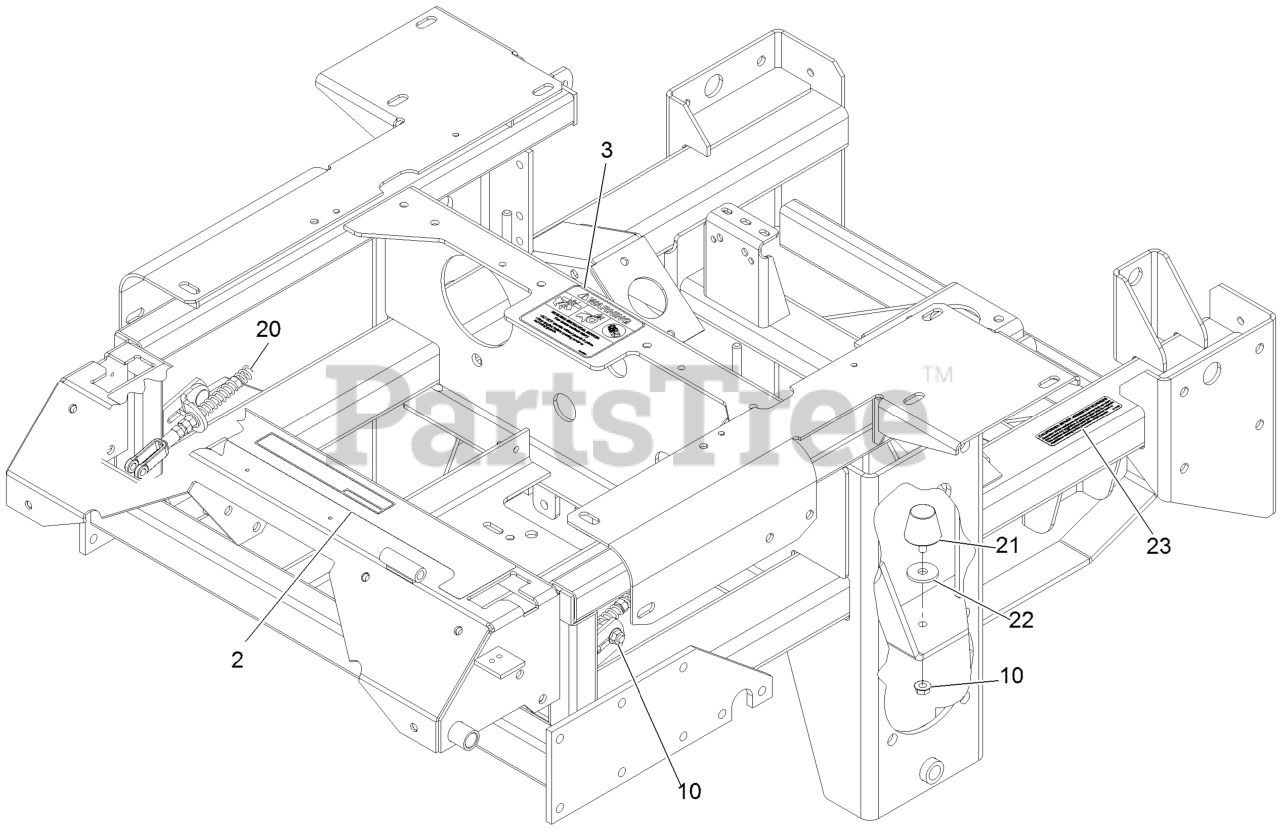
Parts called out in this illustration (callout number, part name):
2	DECAL-CONSOLE, TOP
3	DECAL,WARNING
20	NEUTRAL RETURN ASM
21	BUMPER-RUBBER
23	DECAL-ARRESTER, SPARK
